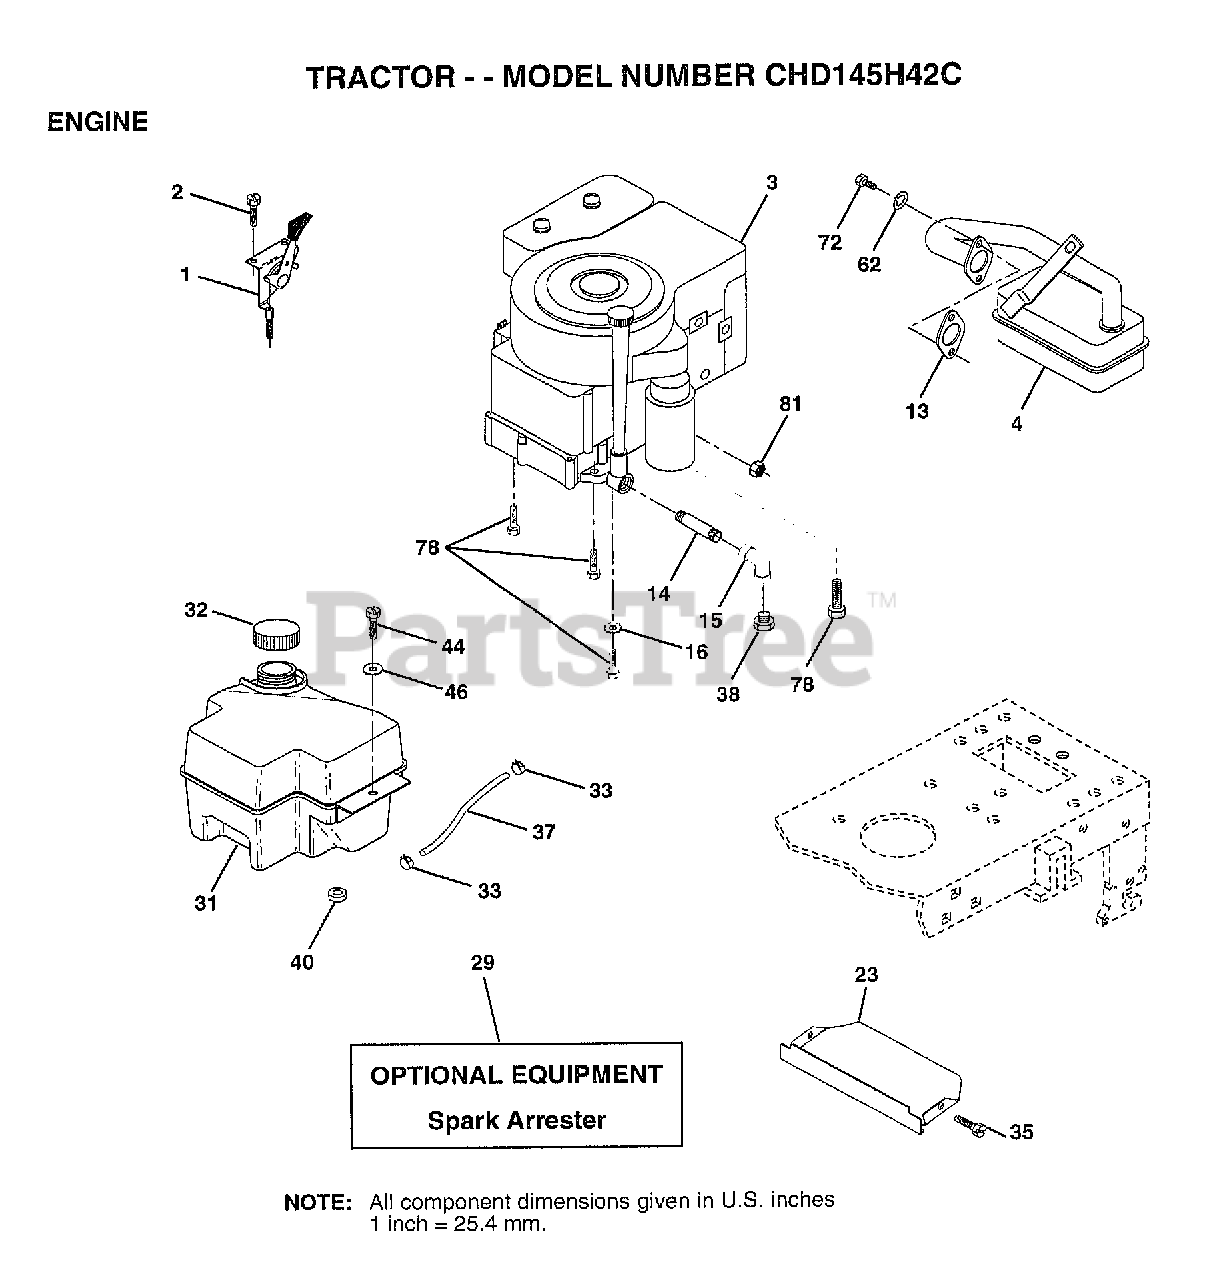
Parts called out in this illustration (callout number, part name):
1	CONTROL THROTTLE
2	SCREW LT
4	MUFFLER
13	GASKET ENG 1 313 LD TIN PLATED
14	PIPE NIPPLE
15	ELBOW
16	LOCKWASHER
23	SHIELD.BRN/DBR.GD
31	TANK.FUEL.FRONT.
32	CAP ASM FUEL
33	HOSE CLAMP
35	SCREW
37	LINE FUEL
44	SCREW HEX CRT
46	WASHER
62	LOCKWASHER
72	SCREW
78	SCREW
81	NUT
